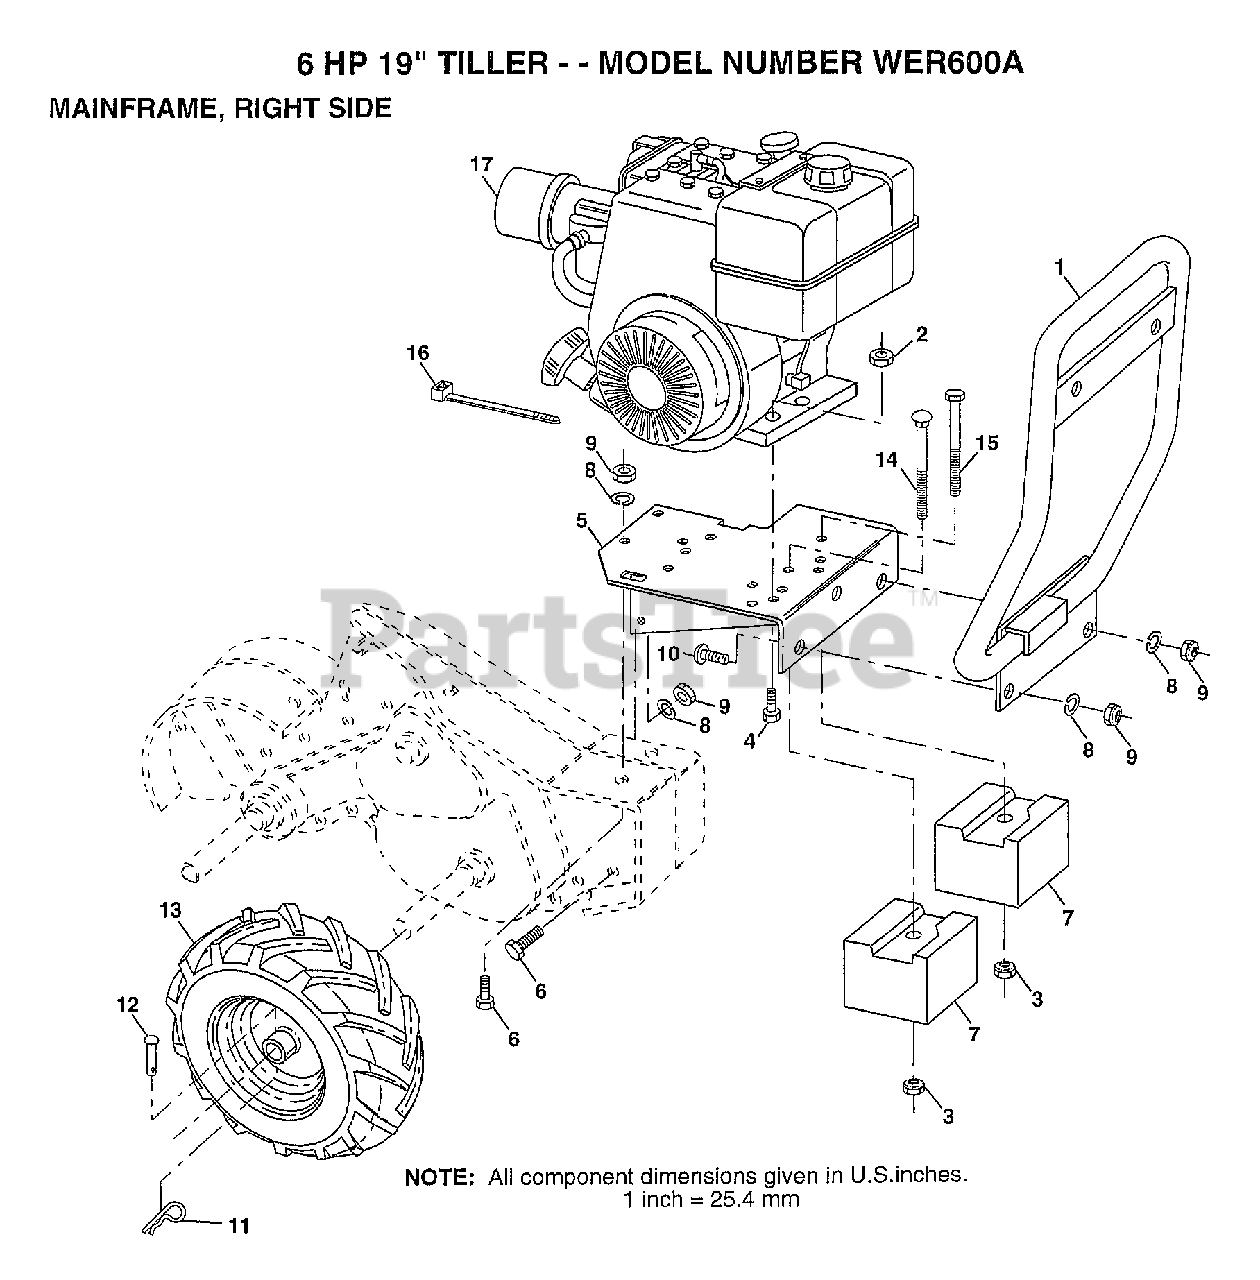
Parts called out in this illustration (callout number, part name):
1	BUMPER.ASM
4	BOLT
5	"ASM. ENGINE, BASE"
6	BOLT
7	COUNTERWEIGHT CRT
8	LOCKWASHER
9	NUT.HEX.3/8-16UNC
11	SPRING.RETAINER
12	RIVET.PAN HD.1.75
13	TIRE TI
13	RIM.16X4X8.WHT
14	BOLT CRT
15	BOLT.3/8-16X4.5
16	TIE CABLE CRT
